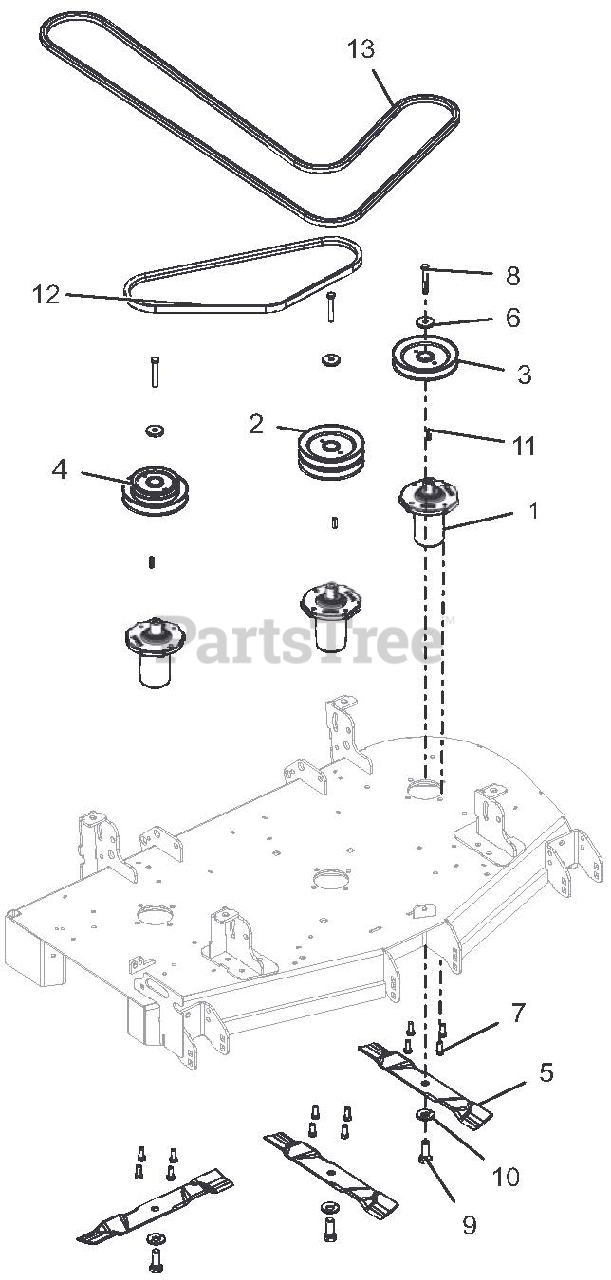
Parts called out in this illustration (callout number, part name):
1	SERVICE, ASM SPINDLE- DUCTILE
2	PULLEY, DOUBLE-1" ID X 5.75" OD-BLACK
3	PULLEY, V - 1" ID X 5.75" OD-BLACK
4	PULLEY, DOUBLE -1" ID X 5.75" & 4.25" OD
5	BLADE, 16.19" MOWER
6	RETAINER, SHEAVE SPINDLE
7	BLT-HEX .38-16X1.00 GR5 YWZC EP30
8	BLT-HEX .38-16X2.75 GR8 YWZC
9	BLT, HEX .62-18X1.75 GR8 YWZC
10	WSHR, BLVL .63X1.625X.14
11	KEY-SQ .250X.250X1.00 RC 40-50
12	V-BELT, B-RAW EDGE COGGED
13	BELT, BB 118.00 WRAPPED HEX
